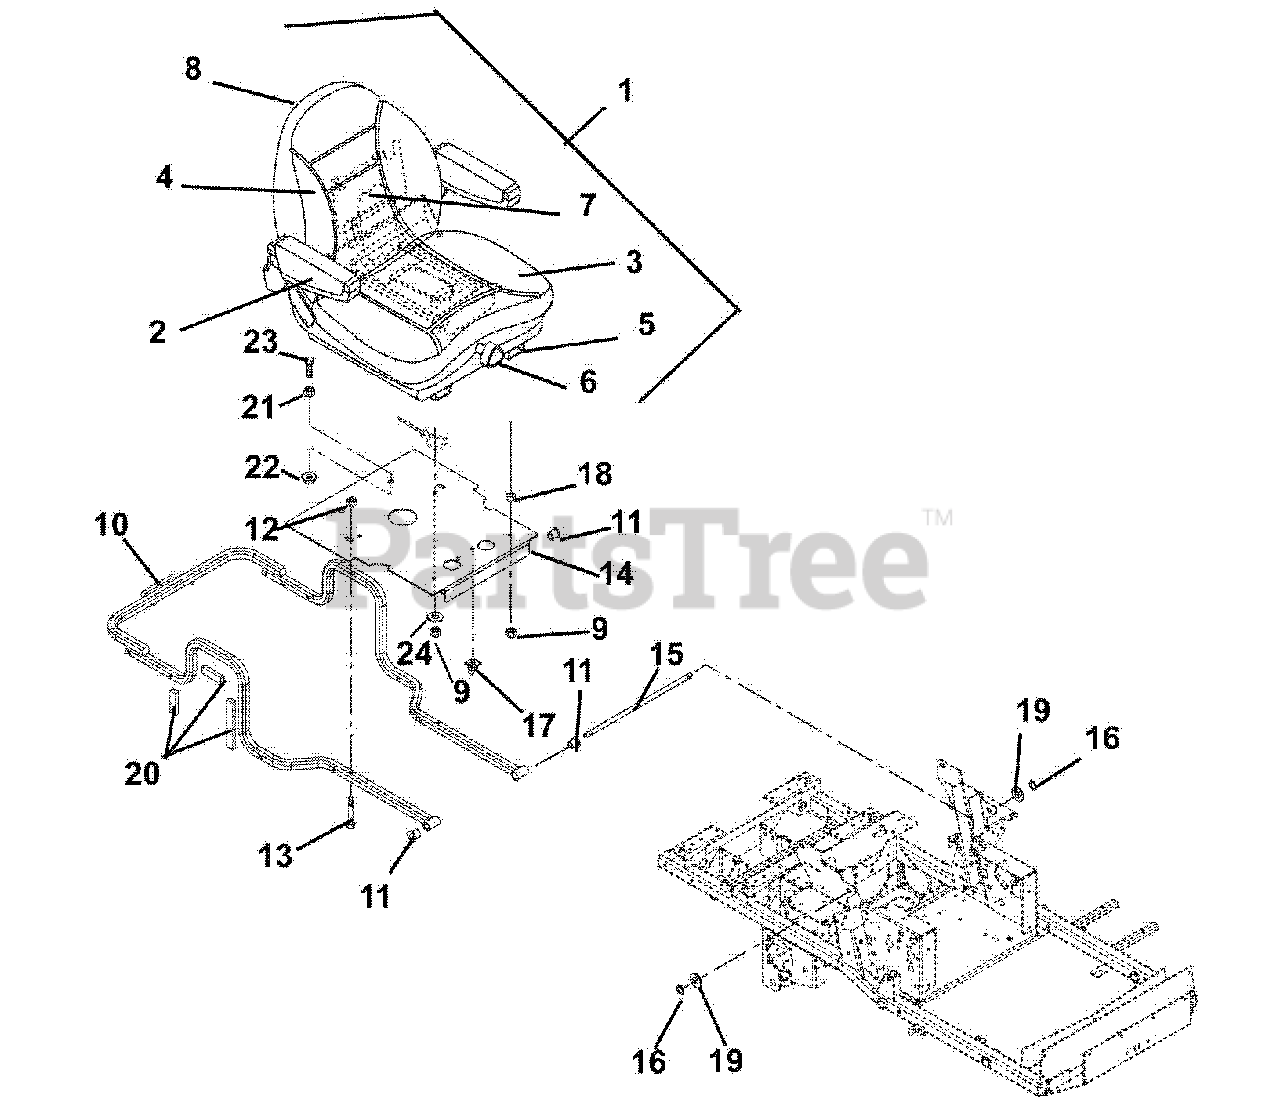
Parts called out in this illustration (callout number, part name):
1	Seat, Suspension, Light Gray
2	Kit, Arm Pad (1 per bag)
3	Kit, Seat Cushion, Light Gray
4	Kit, Back Cushion, Light Gray
5	Kit, Seat Slide
6	Kit, Seat Knob
7	Kit, Spring and Saddle
8	Kit, Seat Back Panel
9	Nut, Locking Top Flange .31-18
10	Weldment, Hood Frame
11	Bushing, Flange .515 x .750 x .745 x 1.00
12	Nut, Locking Top Flange .38-16
13	Bolt, Rib Neck .38-16 x 1.50
14	Weldment, Seat Pivot Mount
15	Rod, Seat Frame Pivot
16	Ring, Retaining External .500 x .050
18	Bushing, Sleeve .377 x .624 x .235
19	Washer, Flat Steel .531 x 1.06 x .095
20	Tape, VHB
21	Nut, Hex .50-13
22	Nut, Locking Top Flange .50-13
23	Bolt, Hex .50-13 x 1.50
24	Washer, Flat Steel .344 x 1.125 x .135
